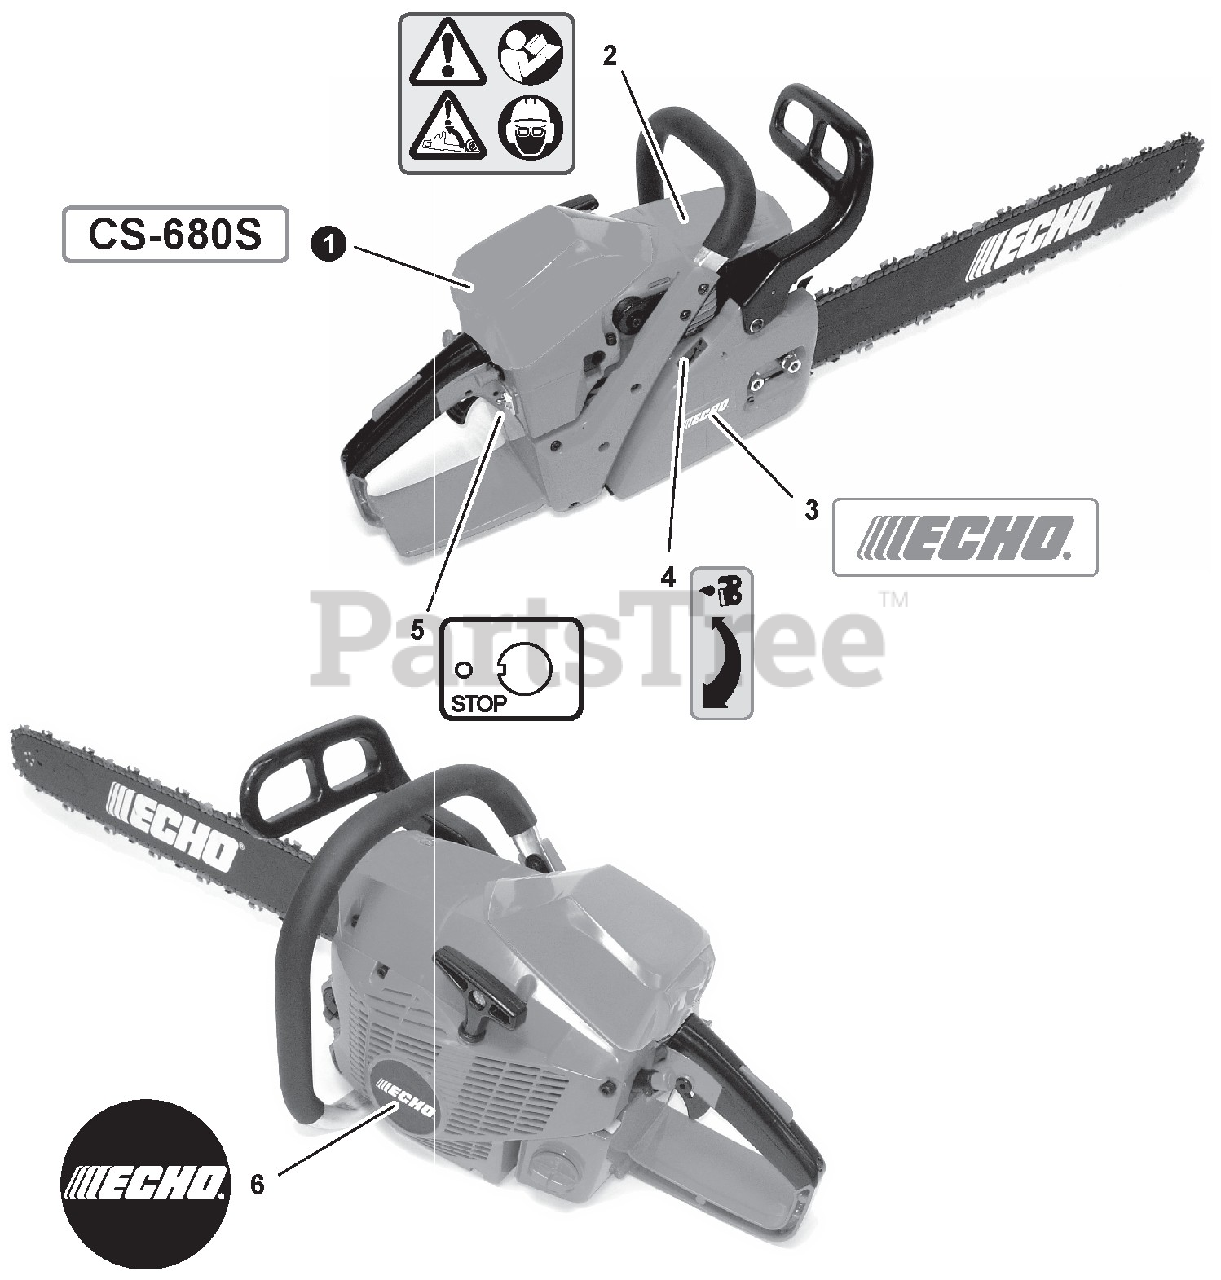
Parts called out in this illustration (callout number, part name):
1	LABEL - MODEL CS-680S
2	LABEL - CAUTION
3	LABEL - ECHO
4	LABEL - CAUTION
5	LABEL - STOP
6	LABEL - ECHO
